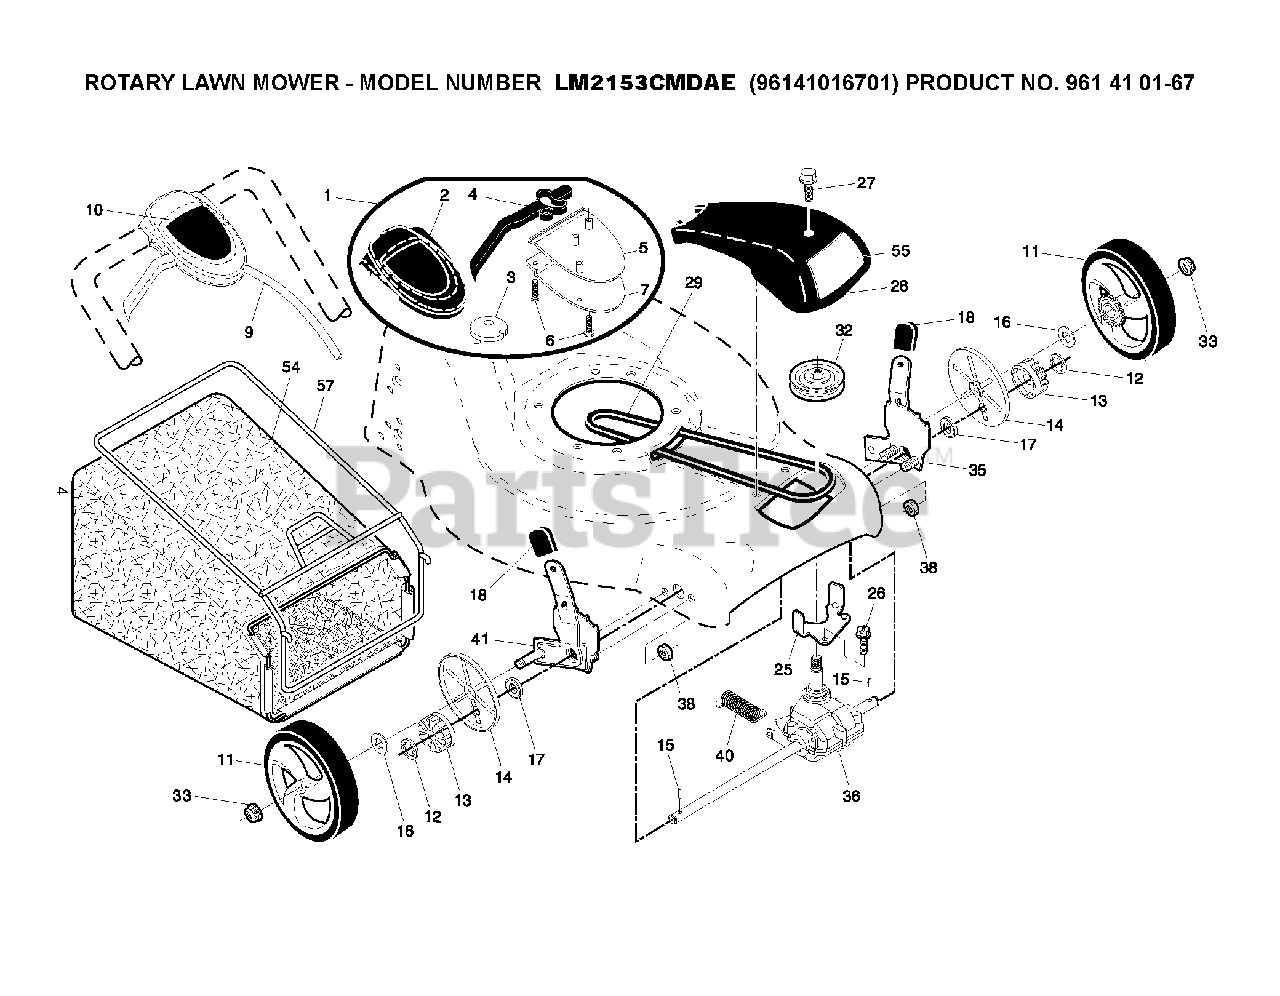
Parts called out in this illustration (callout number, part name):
1	CONTROL.DR.EZ.FGD.SHORT.BK/RED
2	COVER, TOP DRIVE CONTROL
3	PULLEY.CAM.DRIVE.CONTROL.EZ
5	COVER BOTTOM DRIVE CNTRL BLACK
6	SCREW, PHILLIPS HEAD 10 X 5/8
7	BRACKET.DRIVE.CONTROL.MOUNT
9	CABLE ASSEMBLY, DRIVE
12	E-RING 7/16 RE
13	PINION.14.TEETH.FGD
14	COVER.DUST.WHEEL
15	PAWL, DRIVE
16	WASHER FLUT
17	BEARING
18	SELECTOR KNOB
25	BELT KEEPER
27	SCREW, HEX HD TAPPING #10-24 1
29	BELT.DRIVE.FG
32	RP PULLEY.DRIVE.EZ
33	NUT.HEX.FLANGE.3/8-16.LOCKNUT
35	WHEEL ADJ KIT LH
36	TRANSMISSION.21.FGD.HT.VST
38	LOCKNUT
41	WHEEL ADJ KIT RH
54	GBAG.34710010.BLACK.GE
57	FRAME.GBAG.21.FWGD
